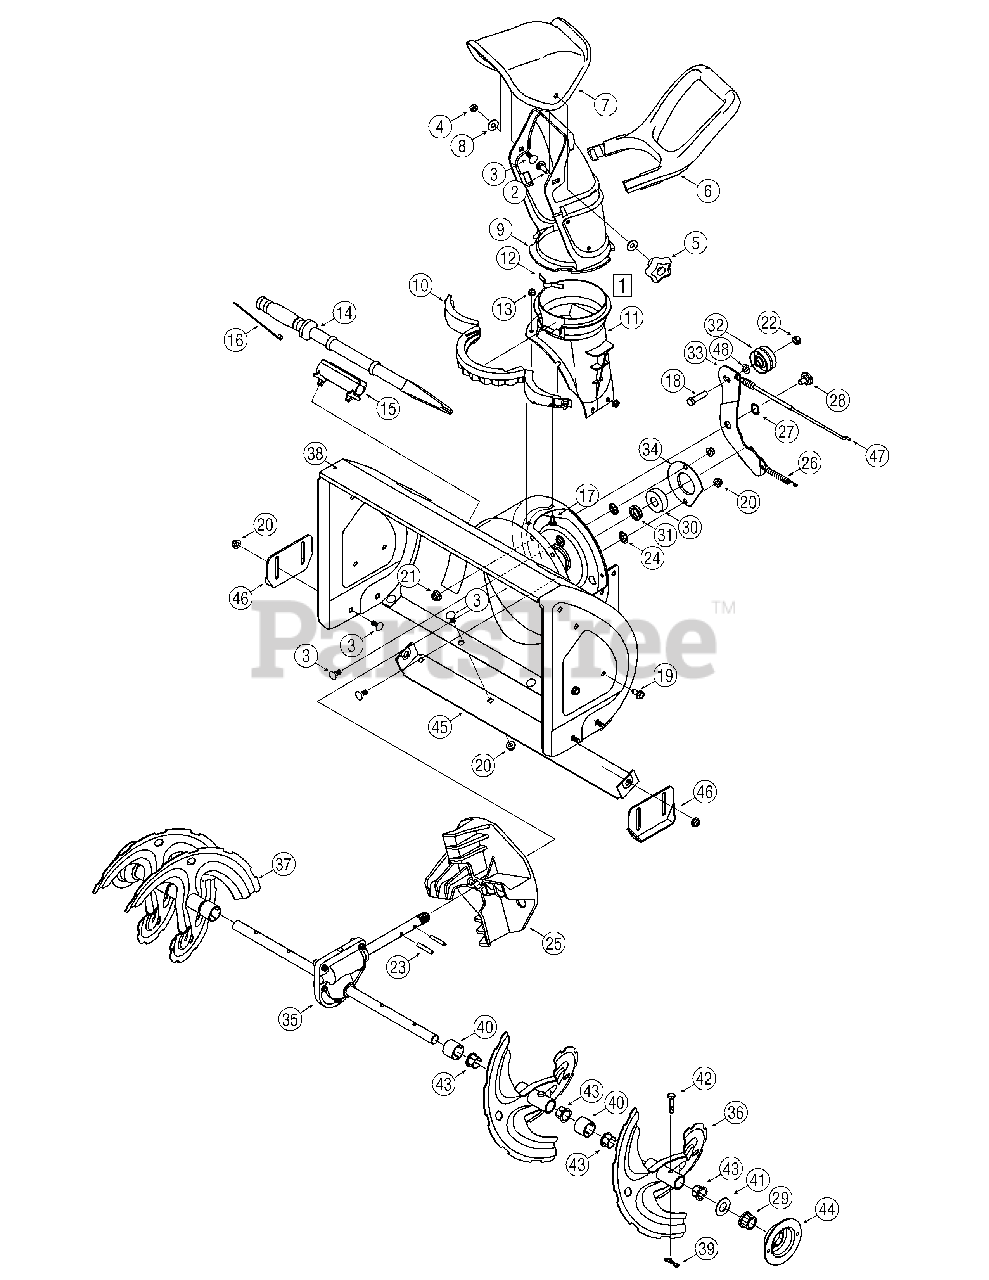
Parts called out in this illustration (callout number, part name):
1	Chute Assembly
2	Carriage Bolt 5/16-18 x 1.0
3	Carriage Bolt 5/16-18
4	Flange Lock Nut, 5/16-18
5	Nut Knob 5/16-18
6	Chute Handle
7	Upper Chute
8	Flat Washer .349 x .879 x .063
9	Lower Chute
10	Chute Ring
11	Chute Adapter 5" Dia.
12	Chute Adjustment Spring
13	Flange Lock Nut 1/4-20
14	Clean-out Tool
15	Clean-out Tool Mount
16	Cable Tie
17	Carriage Screw 1/4-20 x0.62"
18	Hex Bolt 3/8-16 x 1.50"
19	AB Screw 5/16-18 x .625
20	Flange Lock Nut, 5/16-18
21	Flange Lock Nut, 3/8-16
22	Hex Lock Nut 3/8-16
23	Spiral Pin
24	Push On Nut
25	Impeller
26	Extension Spring
27	Wave Washer
28	Shoulder Screw 3/8-16
29	Hex Flange Bearing
30	Ball Bearing
31	Spacer
32	Flat Idler
34	Bearing Housing
35	Auger Gearbox Assembly
40	Spacer, 1.25 x.75 x 1.00
41	Flat Washer
42	Shear Pin,.25 x 1.50
43	Flange Bushing
47	Auger Cable
48	Flat Washer
